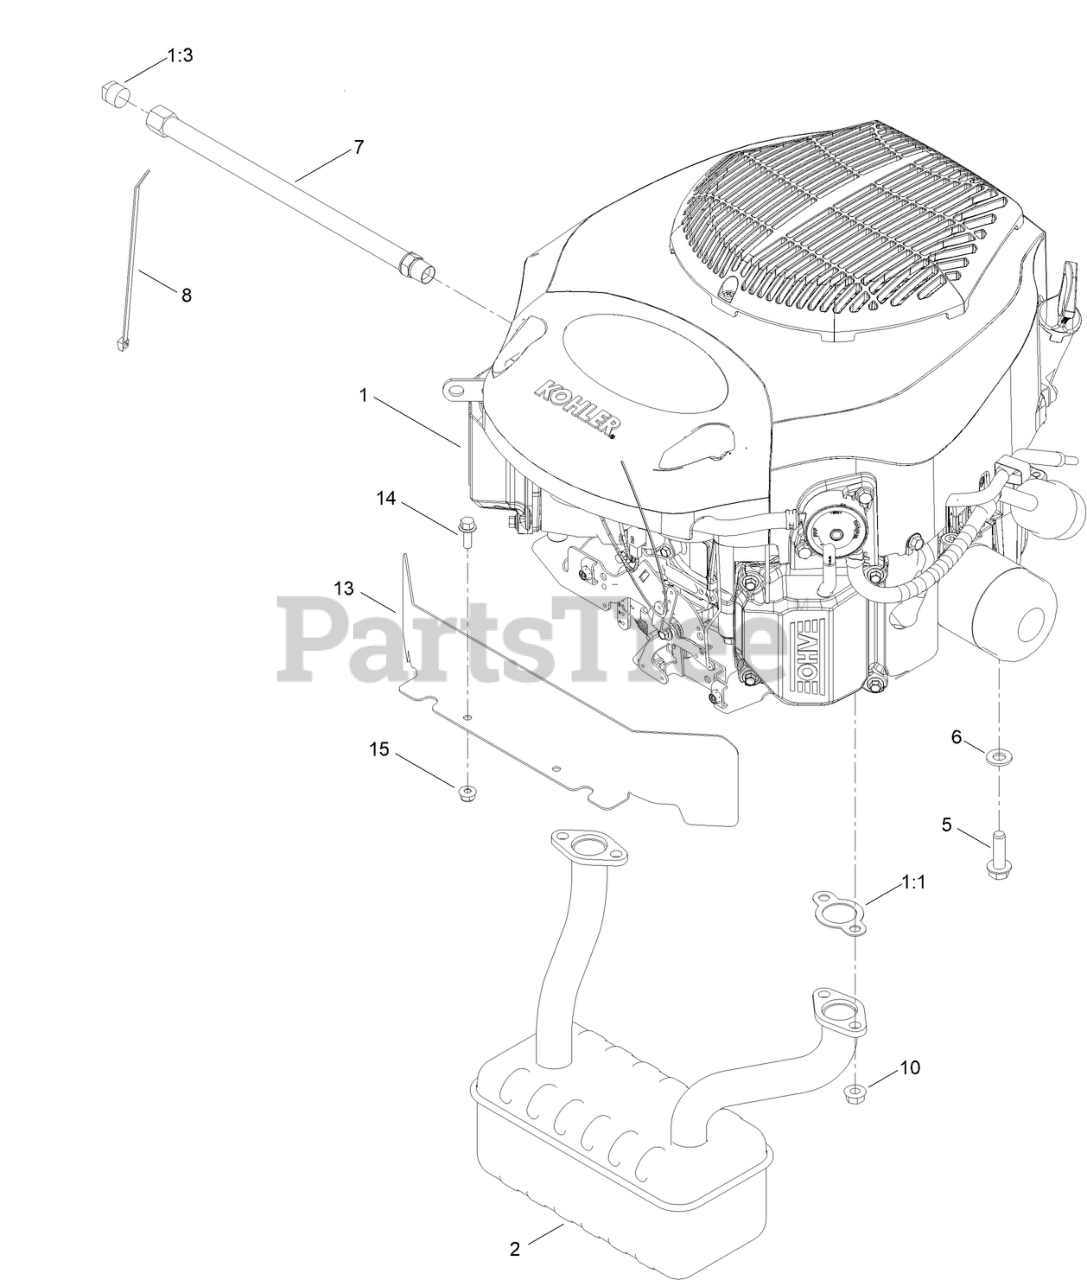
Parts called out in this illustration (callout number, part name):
1	ENGINE-KOHLER, KT735 LOW SPEED
1:1	GASKET-EXHAUST
1:3	PLUG-PIPE, SQH
2	MUFFLER
5	SCREW-HWH, THD ROLL
6	WASHER-FLAT
7	HOSE-DRAIN, OIL
8	TIE-CABLE
10	NUT-HF
13	SHIELD-HEAT
14	SCREW-HHF
15	NUT-FLANGE, NI
